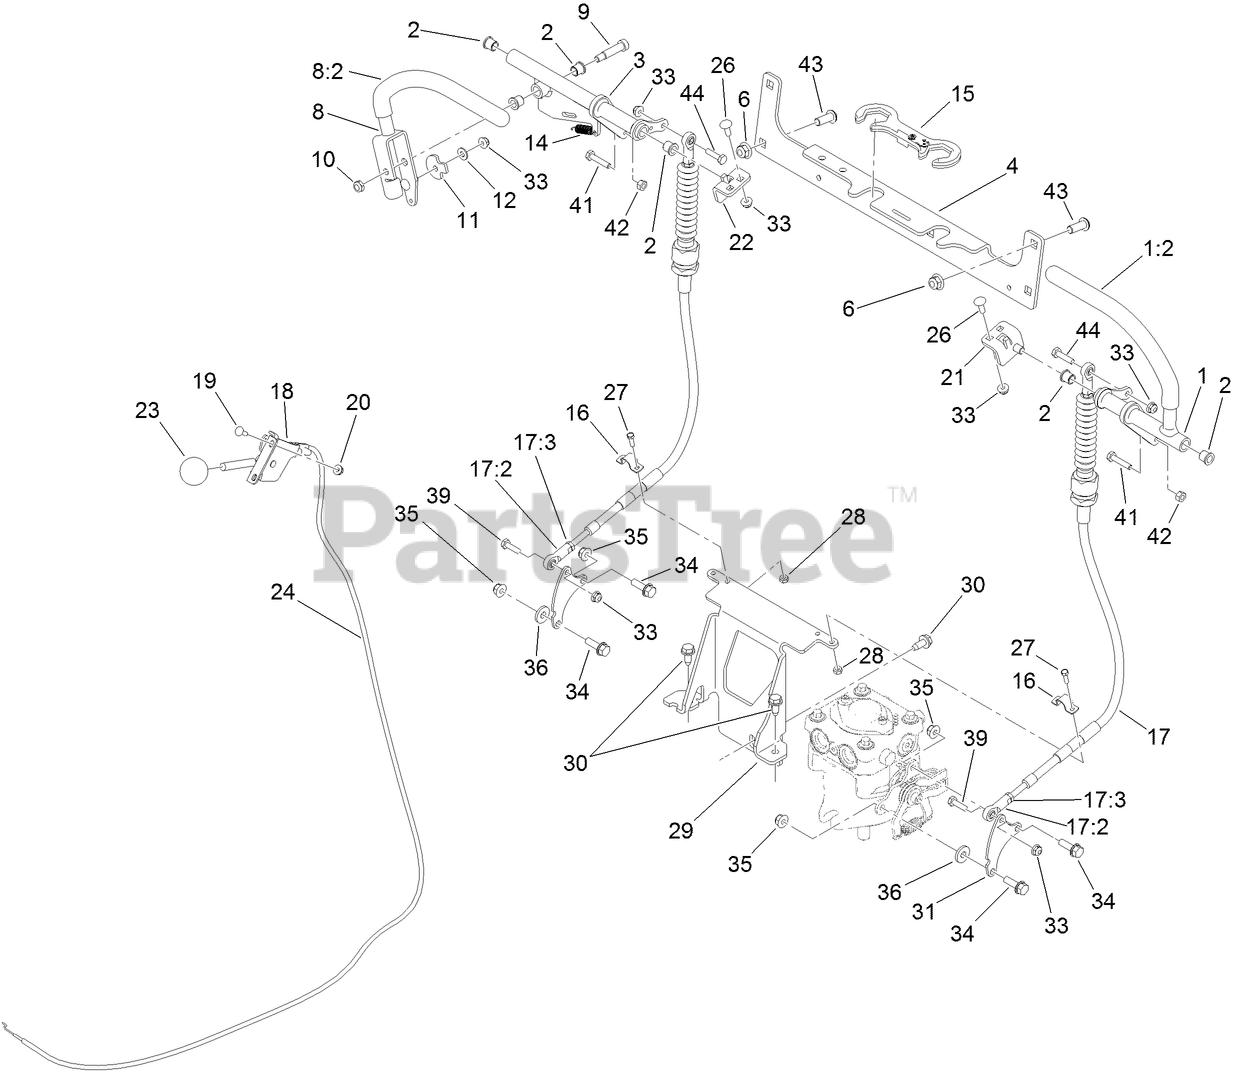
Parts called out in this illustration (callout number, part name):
1	LH LEVER ASM
2	BEARING
3	RH MOTION CONTROL ASM
4	BRACKET-CROSS
6	NUT-HF, NI
8	LEVER-MOTION, RH
9	SCREW-HSH
10	NUT-LOCK, NI
11	CAM-LEVER
12	WASHER-FLAT
14	SPRING-EXTENSION
15	LOCK-CABLE
17	CABLE ASM
17:2	ROD END-BALL JOINT
17:3	NUT-JAM
18	LEVER-CONTROL
19	BOLT-CARR
20	NUT-LOCK, FLANGE
21	LH PIVOT TAB ASM
22	RH PIVOT TAB ASM
23	KNOB-BALL
24	CABLE-THROTTLE
26	BOLT-CARR
28	NUT-LOCK, NI
29	BRACKET-MOUNT, CABLE
30	SCREW-HWHTF
31	PLATE-CONTROL, PUMP
33	NUT-HF
34	SCREW-HHF
35	NUT-HF, NI
36	WASHER-FLAT
39	SCREW-HH
41	SCREW-HH
42	NUT-HEX
43	SCREW-HSBH
44	SCREW-HH
